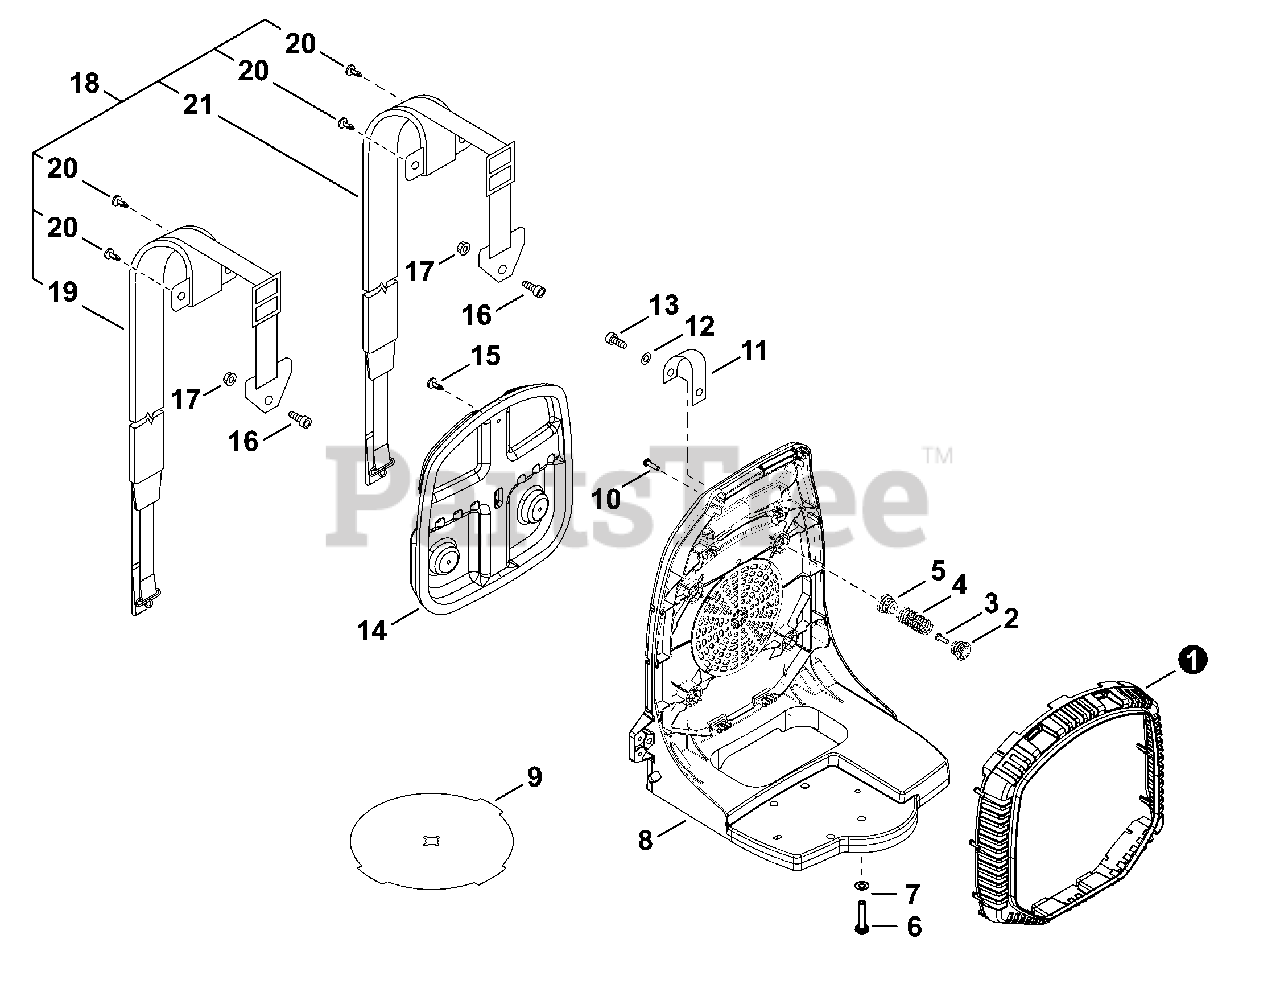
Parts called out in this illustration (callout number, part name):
1	GUARD, DEBRIS
2	HOLDER, SPRING
3	BOLT, TORX 5×16
4	SPRING, COMPRESSION
5	HOLDER, SPRING
6	SCREW 5×25
7	WASHER 5.5×16×2T
8	FRAME, BACKPACK
9	INSERT, COLD WEATHER
10	BOLT, TORX 5×20
11	STRAP, SAFETY 1.2×100
12	WASHER 5.5×16×2T
13	BOLT, TORX 5×20
14	CUSHION, BACKPACK
16	BOLT, TORX 5×30
17	NUT, LOCK M5
18	HARNESS KIT
19	HARNESS ASSY, LEFT
21	HARNESS ASSY, RIGHT
